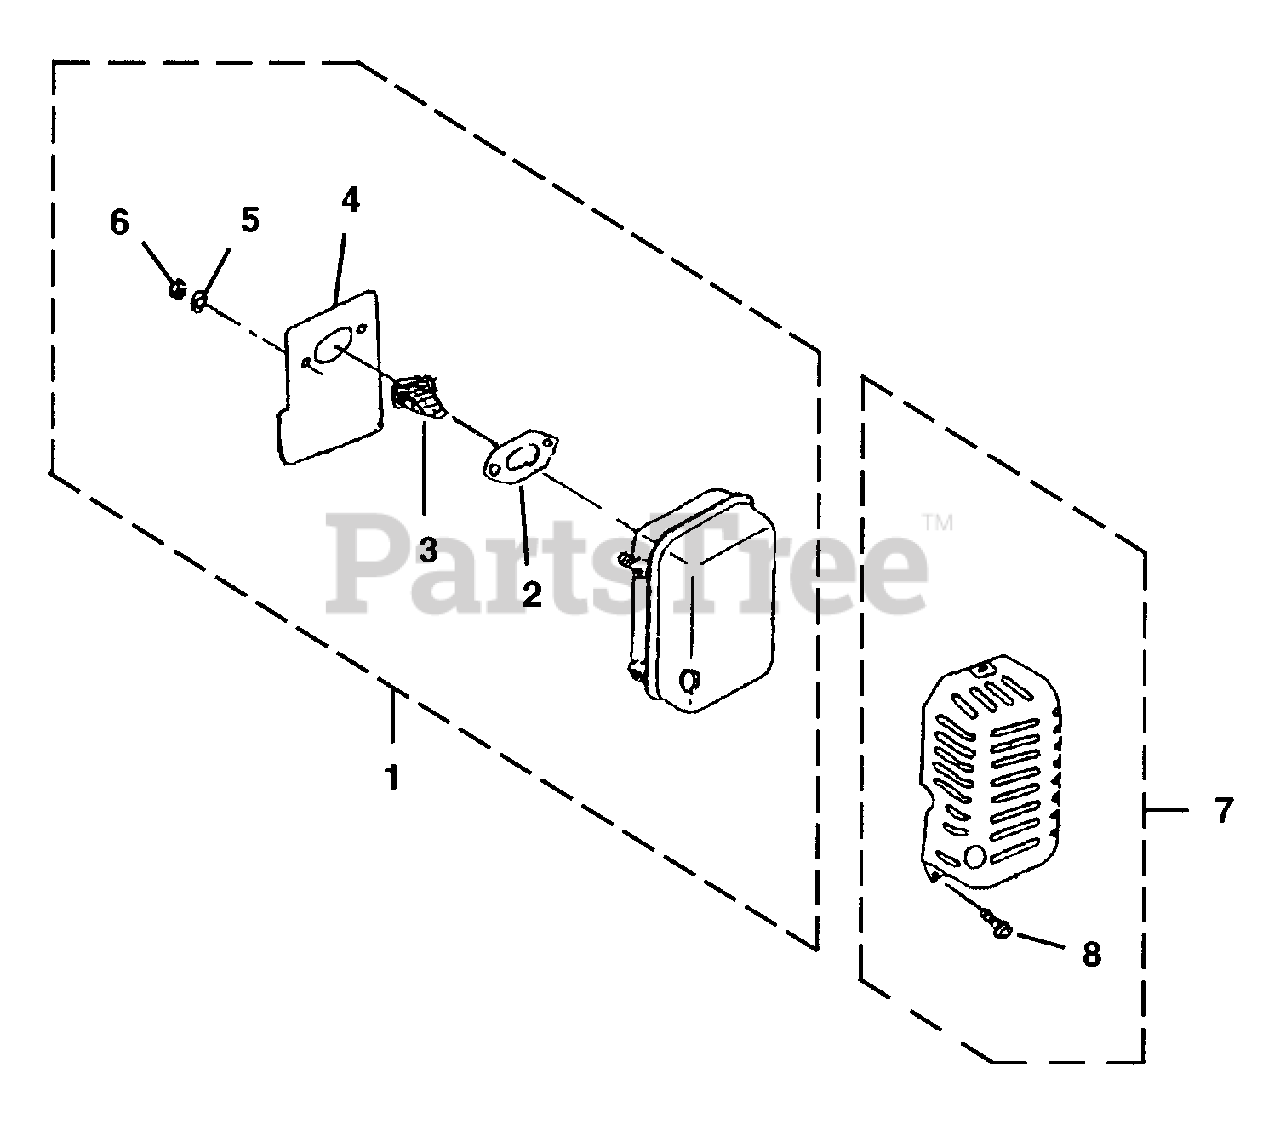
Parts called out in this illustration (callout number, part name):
1	MUFFLER ASSEMBLY
2	GASKET - Muffler
3	SPARK ARRESTER
4	GASKET - Muffler
5	WASHER-Spring
7	MUFFLER COVER
8	SCREW
